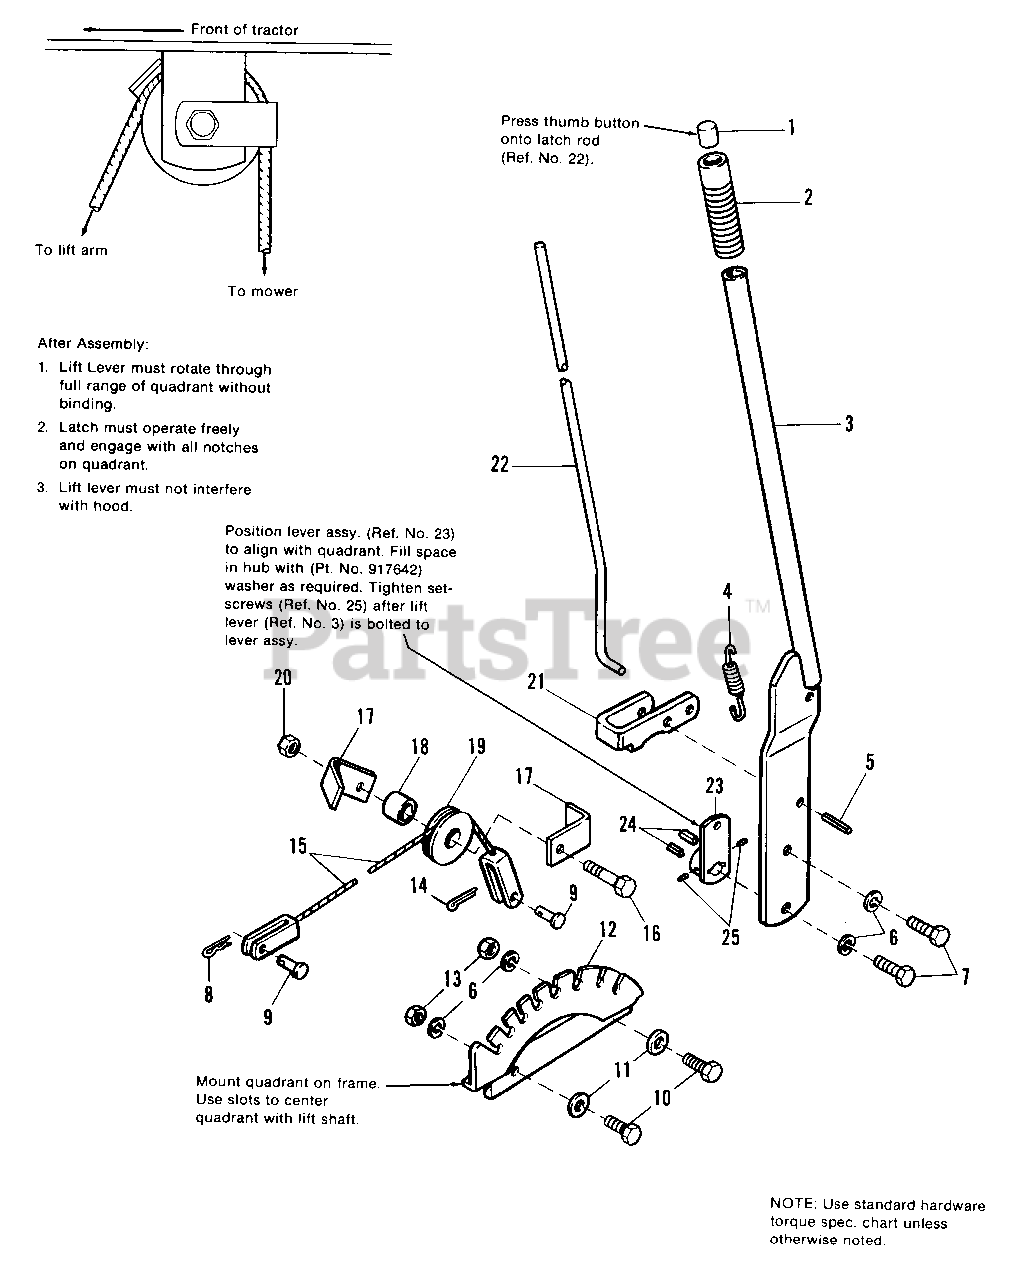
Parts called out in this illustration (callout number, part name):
2	GRIP
3	LEVER ASSY., Lift
5	PIN, Spring, 3/8 x 1-1/4
6	LOCKWASHER, 3/8
7	CAPSCREW, Hex Hd., 3/8-16 x 1
8	CLIP, Spring
10	CAPSCREW, Hex Hd., 3/8-16 x 7/8
11	WASHER, Plain, 5/16
13	NUT, Hex, Full, 3/8-16
14	PIN, Cotter, 3/32 x 1
15	CABLE ASSY., Lift
16	SCREW, Special
17	GUARD, Cable
20	LOCKNUT, Hex, Jam, 3/8-16
21	LATCH, Lift Lever
22	ROD, Latch
23	LEVER ASSY., Lift
25	SETSCREW, 5/16-18 x 1/4
